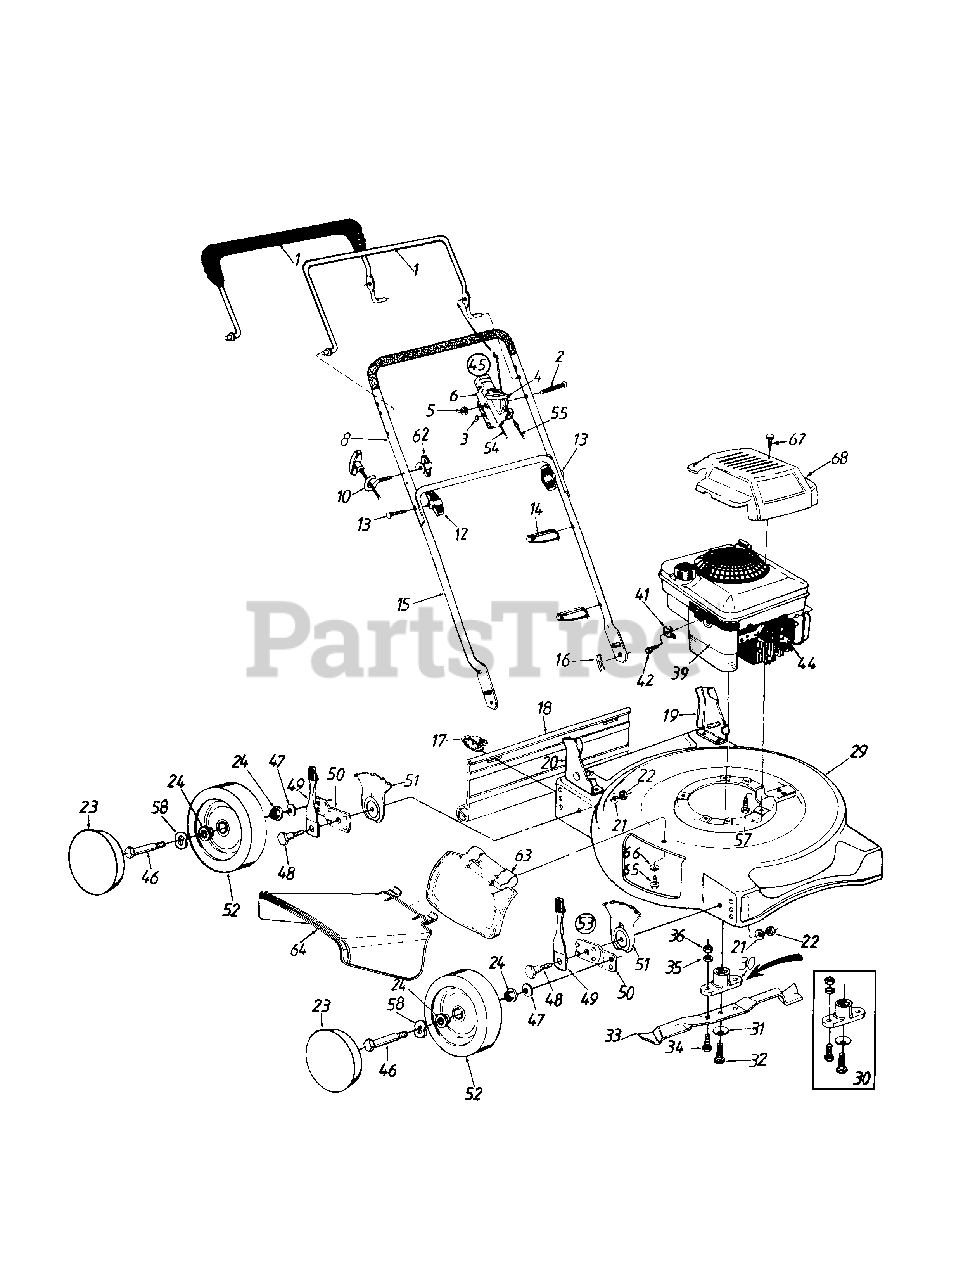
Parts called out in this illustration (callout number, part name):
1	Control Handle Ass'y.
2	Oval C-Sunk Scr.
3	Spr. Wash. .66" I.D.
4	Throttle Lever
5	Hex L-Nut 1/4-20 Thd.
6	Throttle Body
12	Hand Knob
13	Curved Hd. Bolt 5/16-18 x 2" Lg.
14	Cable Tie
16	Hairpin Cotter
17	Hinge Clip
18	Rear Flap
19	Handle Bracket Ass'y.--L.H.
20	Handle Bracket Ass'y.--R.H.
21	Bell-Wash. .39" I.D. x 1.38"
22	Hex Nut 3/8-16 Thd.
23	Hub Cap
24	Bearing
29	20" Deck Ass'y.
30	Blade Adapter Kit
31	Bell-Wash. .46" I.D.
32	Hex Bolt 7/16-20 x 1.5" Lg.
33	20" Mulching Blade
34	Hex Bolt 3/8-24 x 1" Lg.
35	L-Wash. 3/8" I.D.
36	Hex Nut 3/8-24 Thd.
39	Engine
41	Cable Clamp
42	Hex Self-Tap Scr. #10-32 x .62"
44	Spark Plug Boot
45	Throttle Box Comp.
46	Axle Bolt
47	Bell-Wash. .400" I.D. x .88"
48	Shld. Bolt .50" Dia. x .357"
49	Spring Lever Ass'y. w/Knob
51	Height Adj. Plate
52	Wheel Ass'y. Comp.
53	Height Adj. Ass'y. Comp.-- R.F. & L.R.
54	Throttle Cable--51"
55	Control Cable--39"
57	Hex L-Wash. Hd. Scr. 3/8-16 x 1.0" Lg.
58	Wave Washer .51" I.D.
62	Handle Knob 1/4-20 Thd.
63	Mulching Plug
64	Chute Deflector
65	Bell-Wash. 1/4" I.D.
66	Hex Wash. Hd. TT-Tap Scr. 1/4-20 x .5" Lg.
67	Hi-Lo Scr. #10 x 1.25" Lg.
68	Engine Shroud
